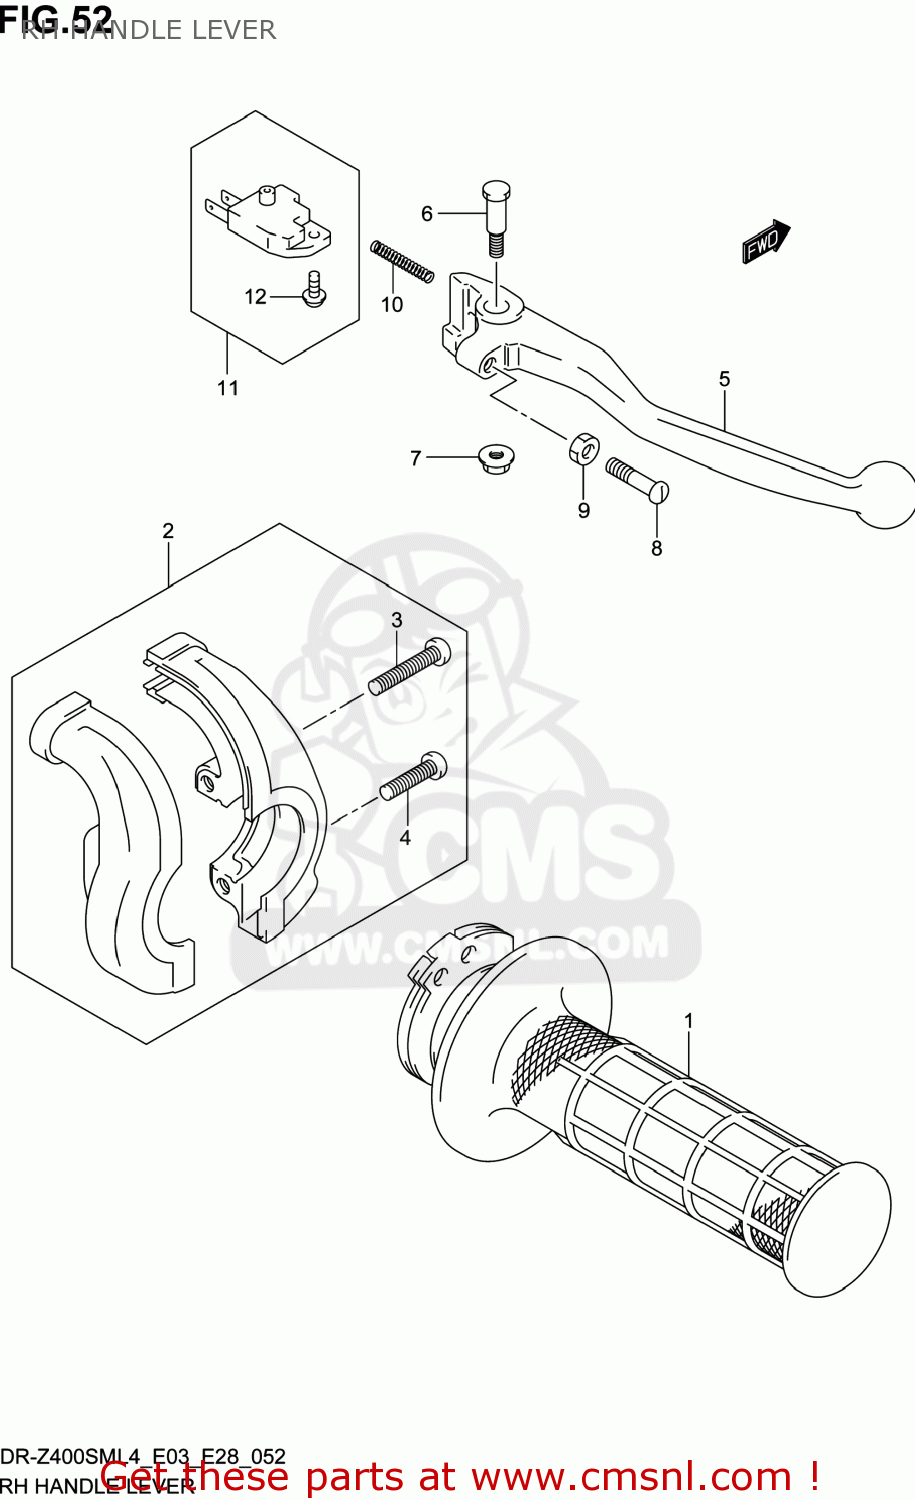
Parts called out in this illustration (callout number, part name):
1	GRIP,THROTTLE
2	CASE ASSY,THROTTLE
3	SCREW
4	SCREW
5	LEVER,BRAKE
6	BOLT,BRAKE LEVER
7	NUT
8	BOLT,ADJUST
9	NUT
10	SPRING,RETURN
11	SWITCH ASSY,FR BRAKE
12	SCREW
